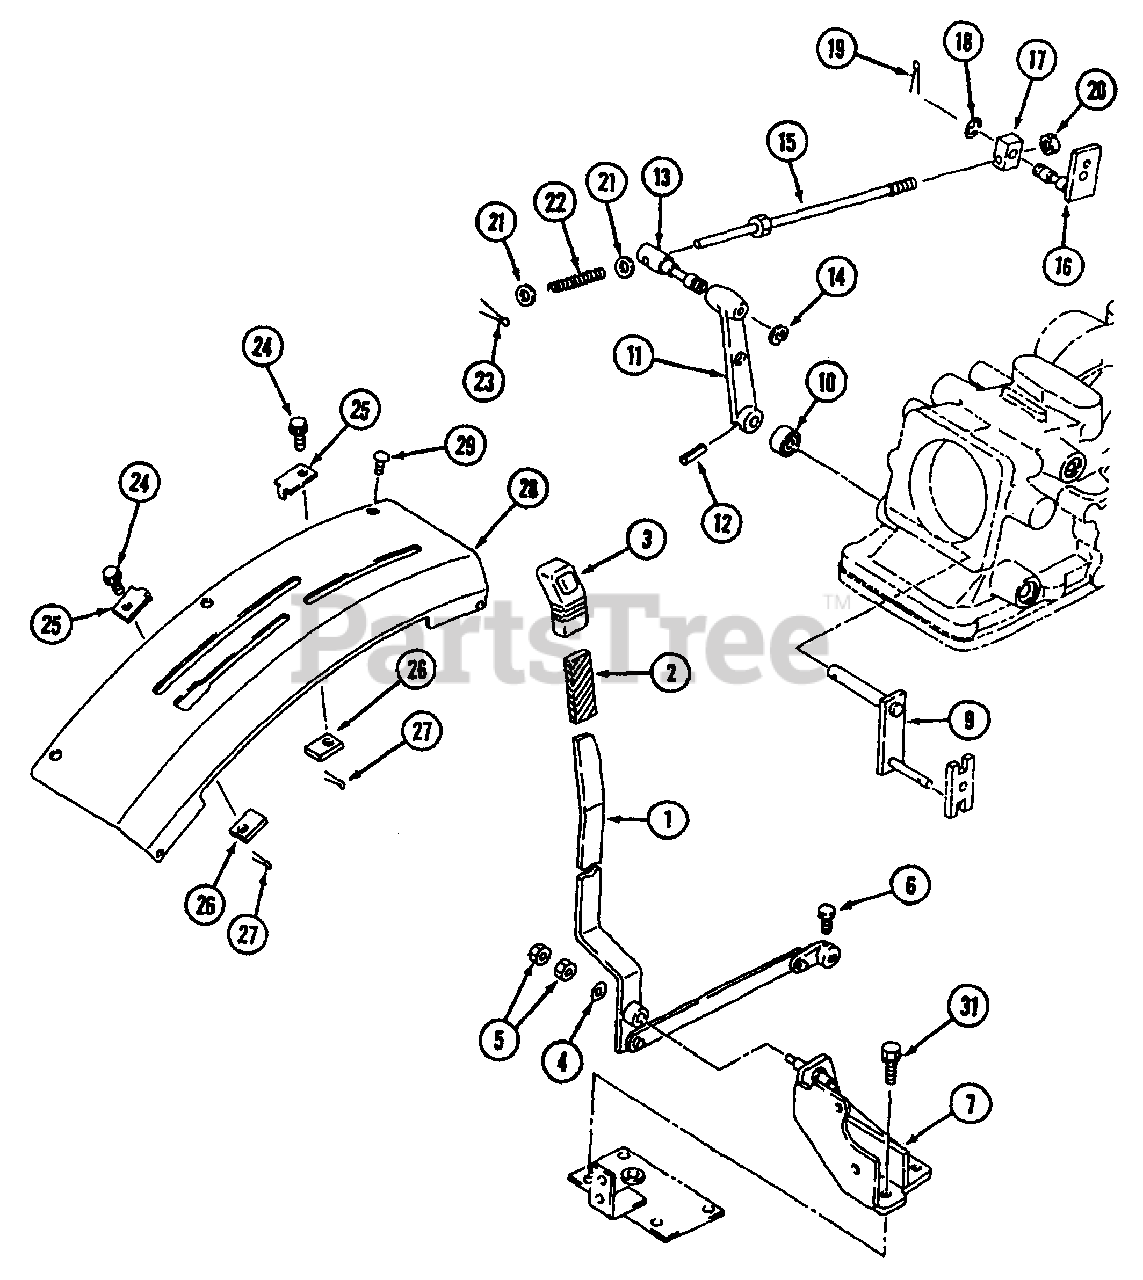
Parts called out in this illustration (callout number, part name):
1	Lever, P/C Ass'y.
7	Bracket, Lever
11	Arm, Feedback
15	Link, Feedback
19	Pin, Split
23	Pin, Split
28	Lever, Guide R.H.
31	Bolt, W/Washer
